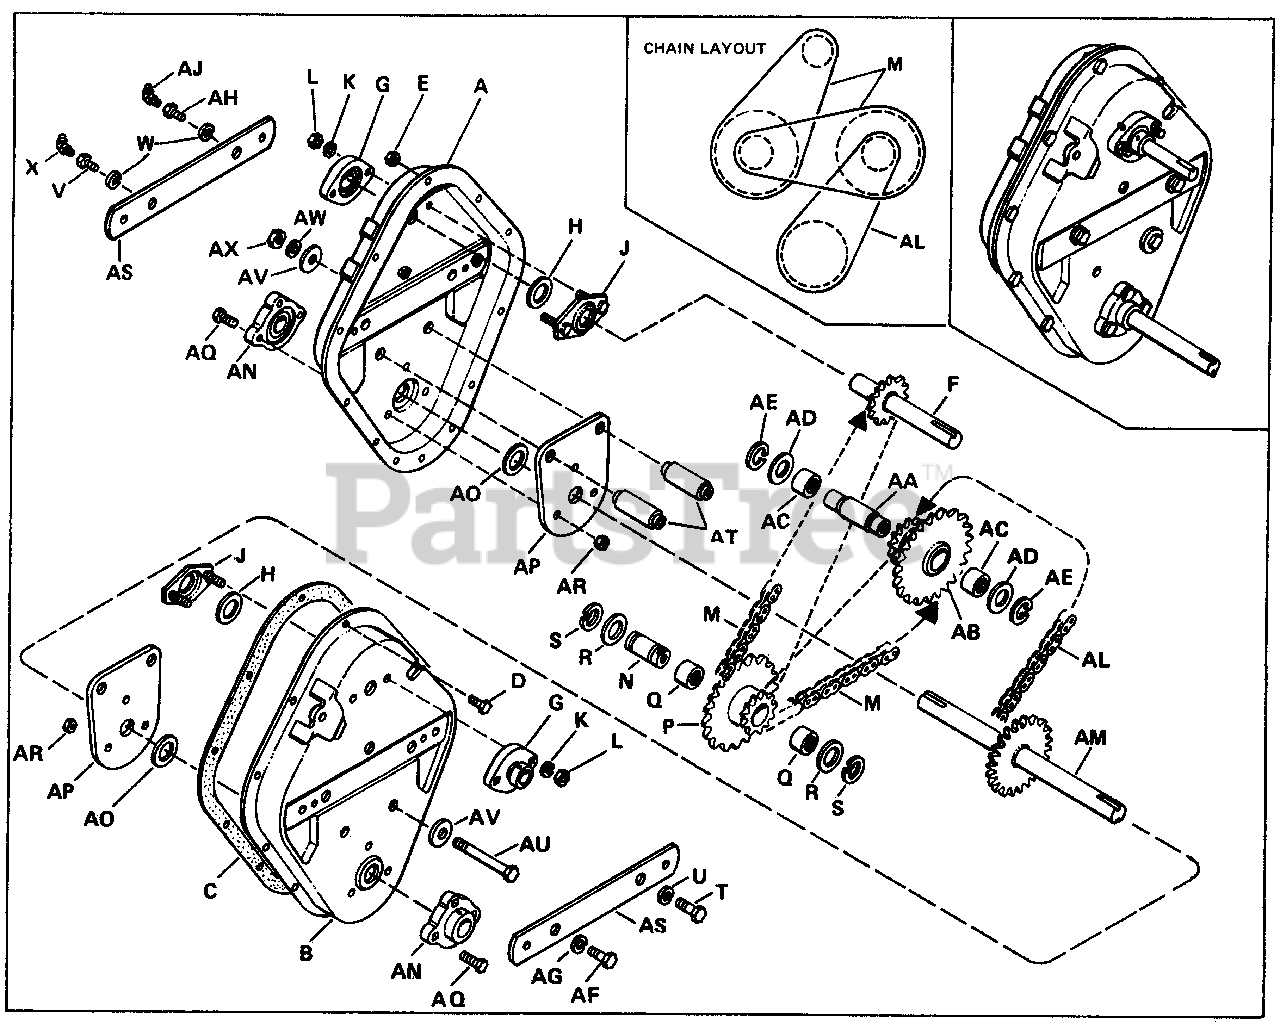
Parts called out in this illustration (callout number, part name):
A	Half Case Assembly, R.H.
B	Half Case Assembly, L.H.
D	Hex. Capscrew, 5/16"-18 x 5/8"
E	Full Hex. Locknut, 5/16"-18
F	Pulley Shaft Assembly
J	Upper Bearing Plate Assembly
K	Lock Washer, 5/16"
L	Full Hex. Nut, 5/16"-18
N	Inter. Spacer
P	Sprocket Assembly
Q	Roller Bearing
S	Retaining Ring
T	Hex. Capscrew (L.H. Side), 1/2"-20 x 1 1/4"
U	Lock Washer, 1/2"
V	Bolt, (R.H. Side)
W	Lock Washer,1/2"
X	Grease Fitting
AA	Inter. Spacer
AB	Sprocket Assembly
AC	Roller Bearing
AE	Retaining Ring
AF	Hex. Capscrew (L.H. Side), 1/2"-20 x 1 1/4"
AG	Lock Washer, 1/2"
AH	Bolt (R.H. Side)
AJ	Grease Fitting
AM	Tine Shaft Assembly
AP	Reinf. Plate
AQ	Thread Forming Screw 3/8"-16 x 1 1/2"
AR	Hex. Jam Locknut, 3/8"-16
AS	Side Bar, 3/16" x 2" x 13-1/16"
AT	Spacer, 1" x 7/32" x 3 1/32"
AU	Hex. Capscrew, 1/2"-13 x 4"
AV	Plain Washer, 1/2"
AW	Lock Washer, 1/2"
AX	Full Hex. Nut, 1/2"-13
